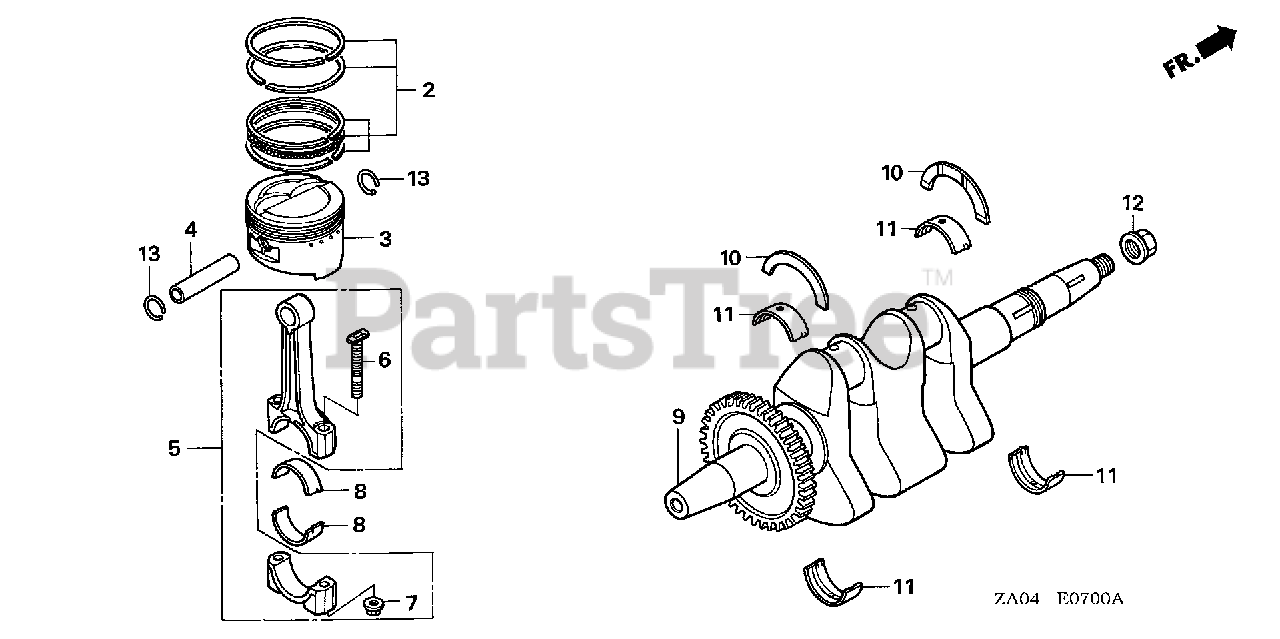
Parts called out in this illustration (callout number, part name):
2	RING SET, PISTON (STD)
2	RING SET, PISTON (OS 0.25)
2	RING SET, PISTON (0.25) (TEIKOKU)
2	RING SET, PISTON (0.50) (RIKEN)
2	RING SET, PISTON (OS 0.50)
3	PISTON (STD)
3	PISTON (OS 0.25)
3	PISTON (OS 0.50)
4	PIN, PISTON
5	ROD ASSY., CONNECTING
6	BOLT, CONNECTING ROD
7	NUT, CONNECTING ROD
8	BEARING A, CONNECTING ROD (Honda Code 0282053). (BLACK)
8	BEARING B, CONNECTING ROD (Honda Code 0282251). (BROWN)
8	BEARING C, CONNECTING ROD (Honda Code 0282285). (GREEN)
8	BEARING D, CONNECTING ROD (Honda Code 0282293). (YELLOW)
8	BEARING E, CONNECTING ROD (Honda Code 0282301). (RED)
9	CRANKSHAFT
10	BEARING, CRANKSHAFT THRUST
11	BEARING, CRANKSHAFT (1) (Honda Code 1278183). (BLACK)
11	BEARING, CRANKSHAFT (2) (Honda Code 1278191). (BROWN)
11	BEARING, CRANKSHAFT (3) (Honda Code 1278217). (GREEN)
11	BEARING, CRANKSHAFT (4) (Honda Code 1278225). (YELLOW)
11	BEARING, CRANKSHAFT (5) (RED)
13	CLIP, PISTON PIN (14MM)
